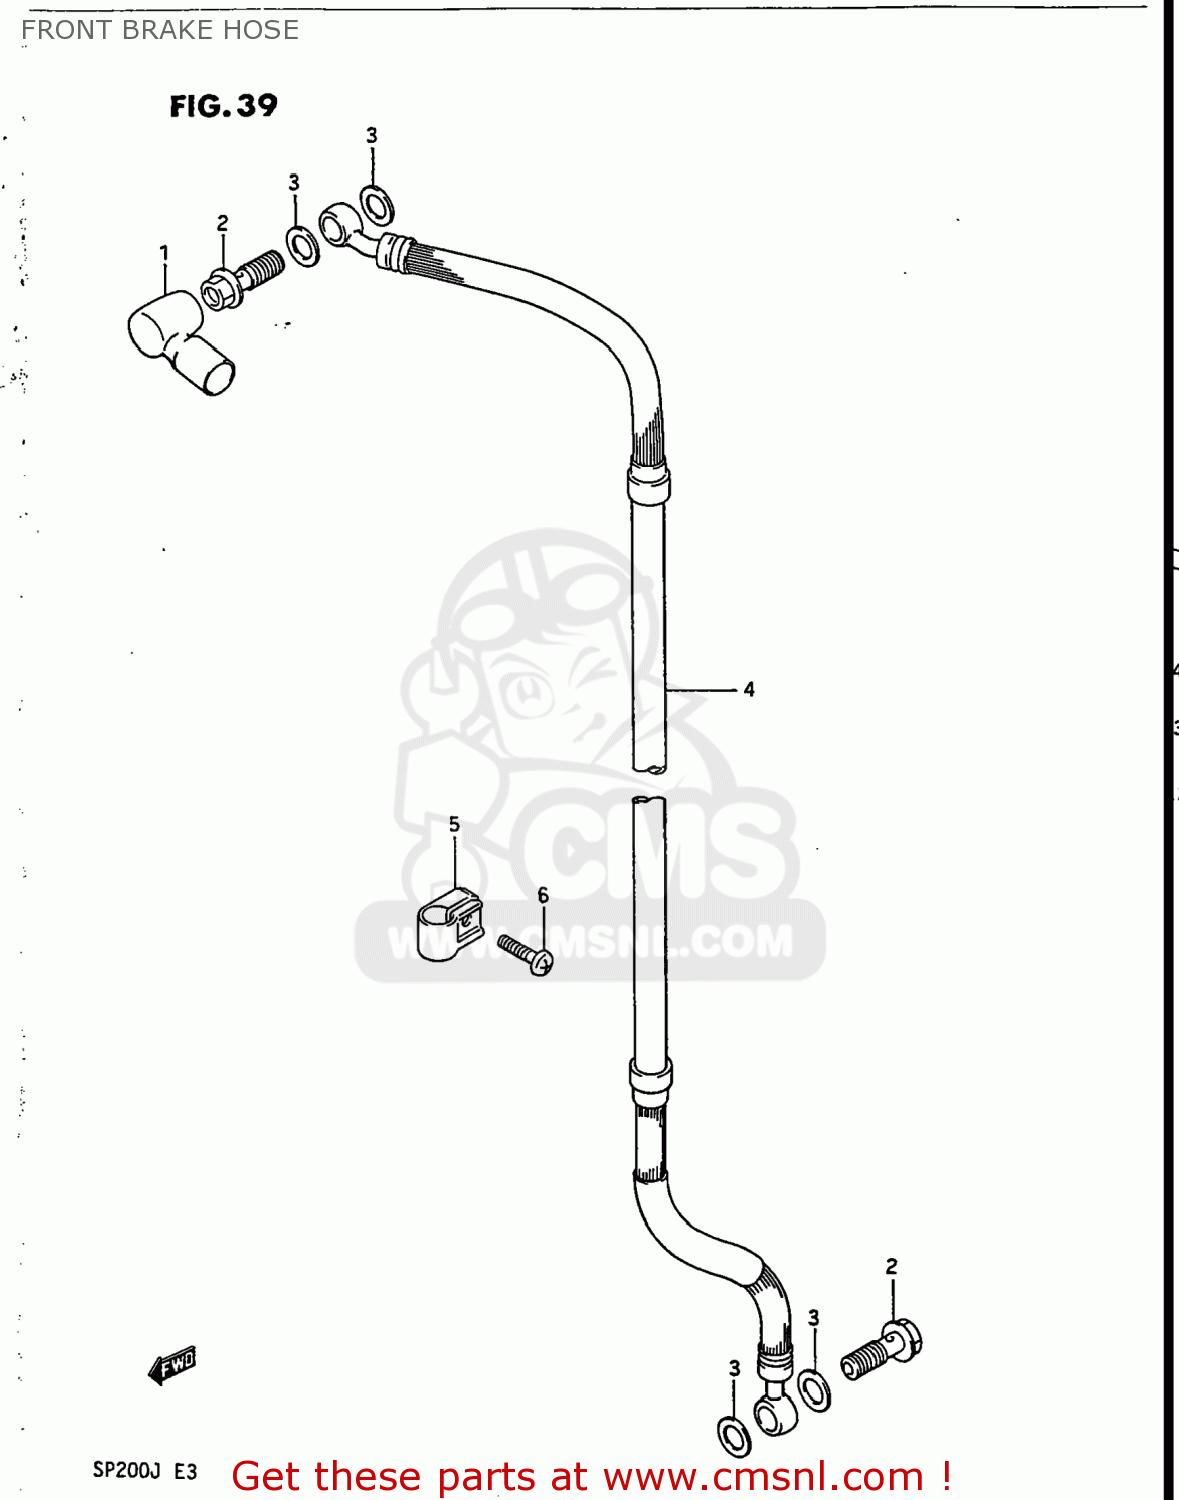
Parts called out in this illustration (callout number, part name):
1	BOOT,MASTER CYLINDER
2	BOLT UNION
3	WASHER(10X15X1.5)
4	HOSE,FRONT BRAKE
5	CLAMP,BRAKE HOSE
6	SCREW
